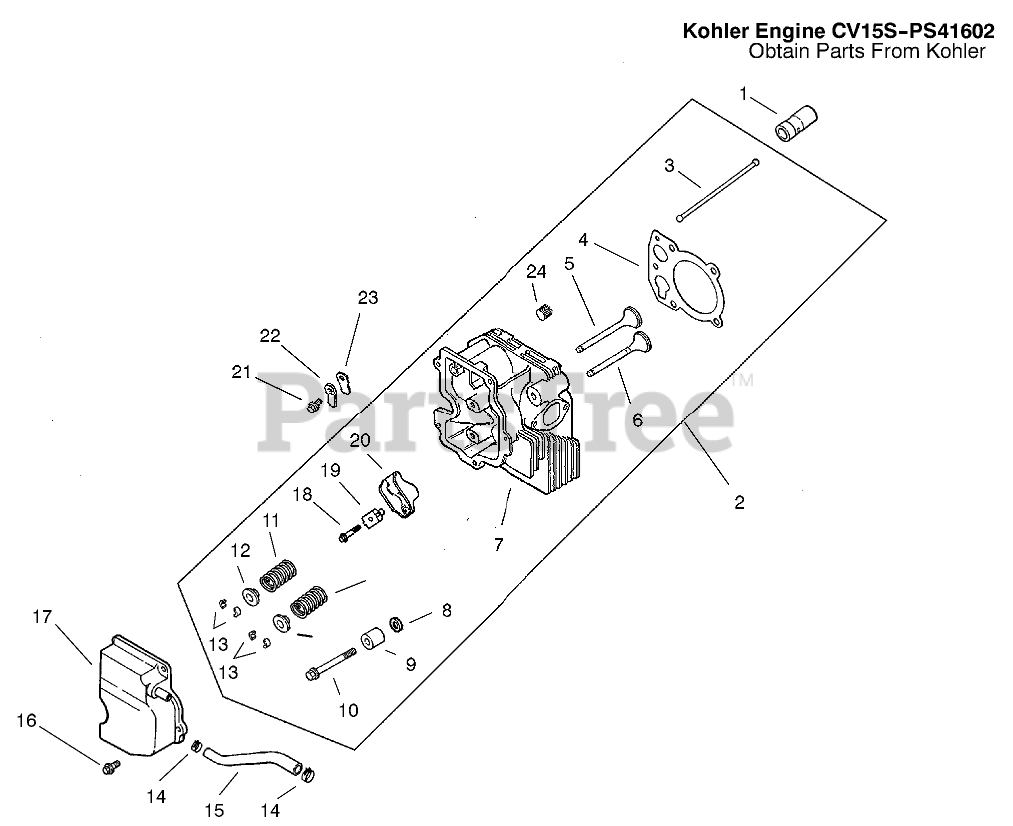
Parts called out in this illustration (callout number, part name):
1	Lifter-Valve
2	gasket)
3	Rod-Push
4	Gasket-Cylinder Head
5	Valve-Intake STD
6	Valve-Exhaust STD
7	Head-Cylinder
8	Washer
9	Spacer-Head Bolt
10	Screw M10x1.5x80
11	Spring-Valve
12	Cap-Spring, Valve
13	Retainer Kit
14	Clamp-Hose
15	Hose-Breather
16	Screw-HF (M6x1.0x20)
17	Cover-Valve w/Nipple
18	Screw-HF (M6x1.0x34)
19	Pivot-Rocker Arm
20	Arm-Rocker
21	Screw (M5x0.8x10)
22	Retainer-Reed
23	Reed-Breather
24	Plug
